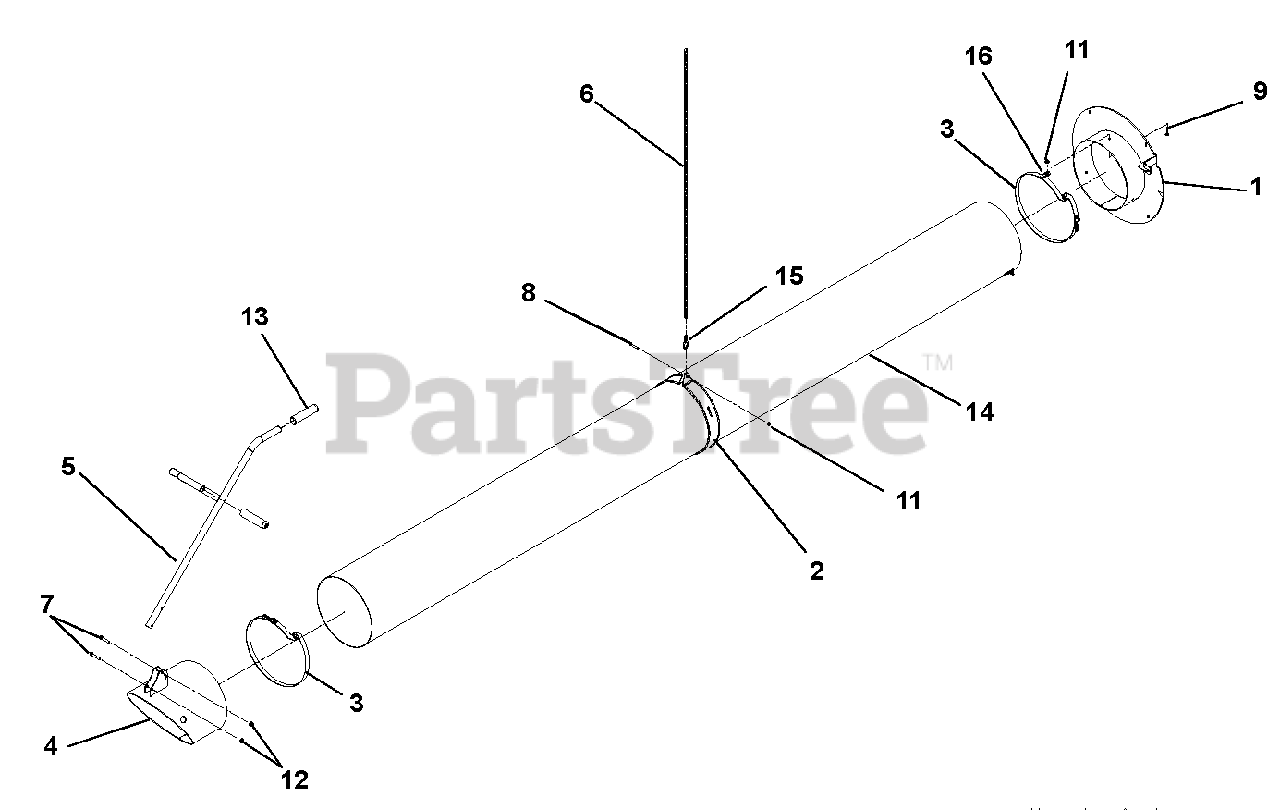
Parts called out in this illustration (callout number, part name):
1	Weldment, Cover Plate (995841)
2	Band, Hose Support 12" (995841)
3	Clamp, Bridge 12" (995841)
4	Weldment, Tube Pickup 12" (995841)
5	Weldment, Handle, Truck Loader
6	Chain, .148 x 5’
7	Bolt, Hex .312-18 x 1.75 Grade 5 YWZC
8	Bolt, Hex .25-20 x 1.75 Grade 5 YWZ
9	Bolt, Round Head Square Neck .25-20 x 1.00 Grade 5 YWZ
11	Nut, .25-20 Nyloc Flange
12	Nut, .31-18 Nyloc Flange YXCZ
13	Grip, Handle
14	Hose, 12" x 12’ Clear (995841)
15	Hook, Spring 2450S-3/16"
16	Clip, Hose
